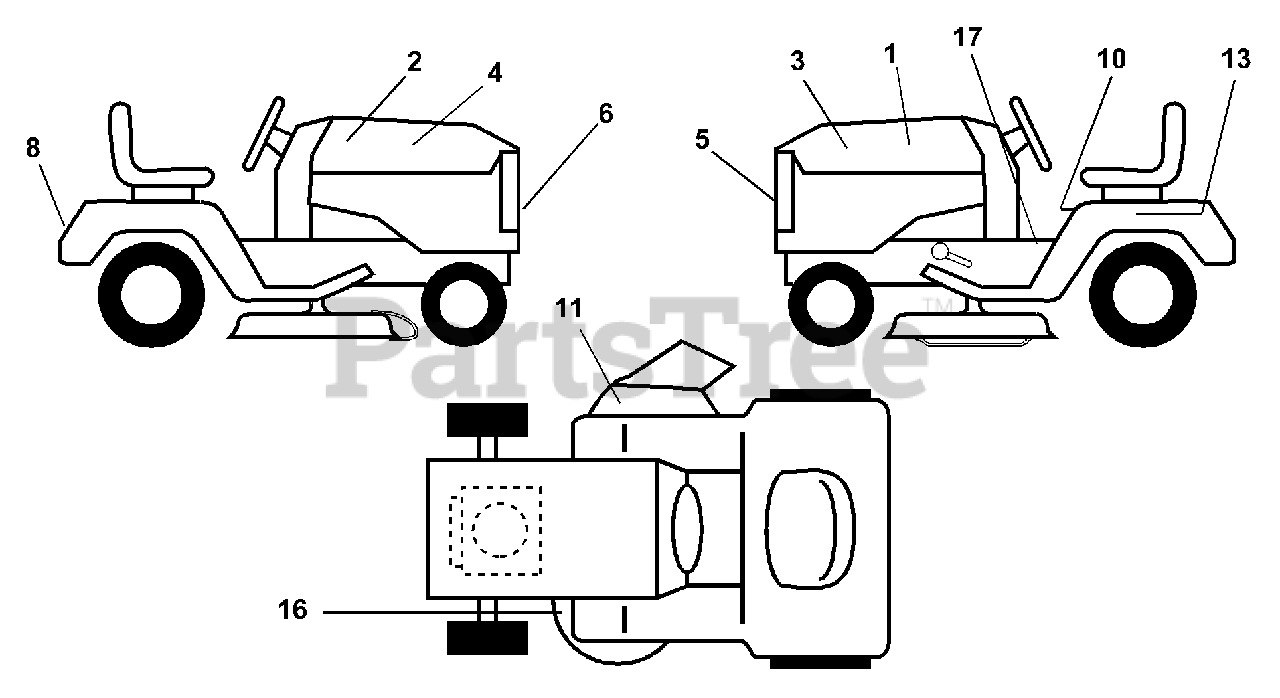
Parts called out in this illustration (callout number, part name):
1	Decal, Hood, L. H., Husqv.
2	Decal, Hood, R. H., Husqv.
3	Decal, Hood, L. H.
4	Decal, Hood, R. H.
5	Decal, Logo, Grill
6	Decal, Lightbox
8	Decal, Logo, Fender
10	Decal Caution Fender
11	Decal, Warning, Cut Finger,
13	Decal, Caution, Battery
16	Decal, V-Belt Sch.
17	Decal, Inst. Oper.
17	Manual, Owner's (French)
17	Manual, Owner's (English)
